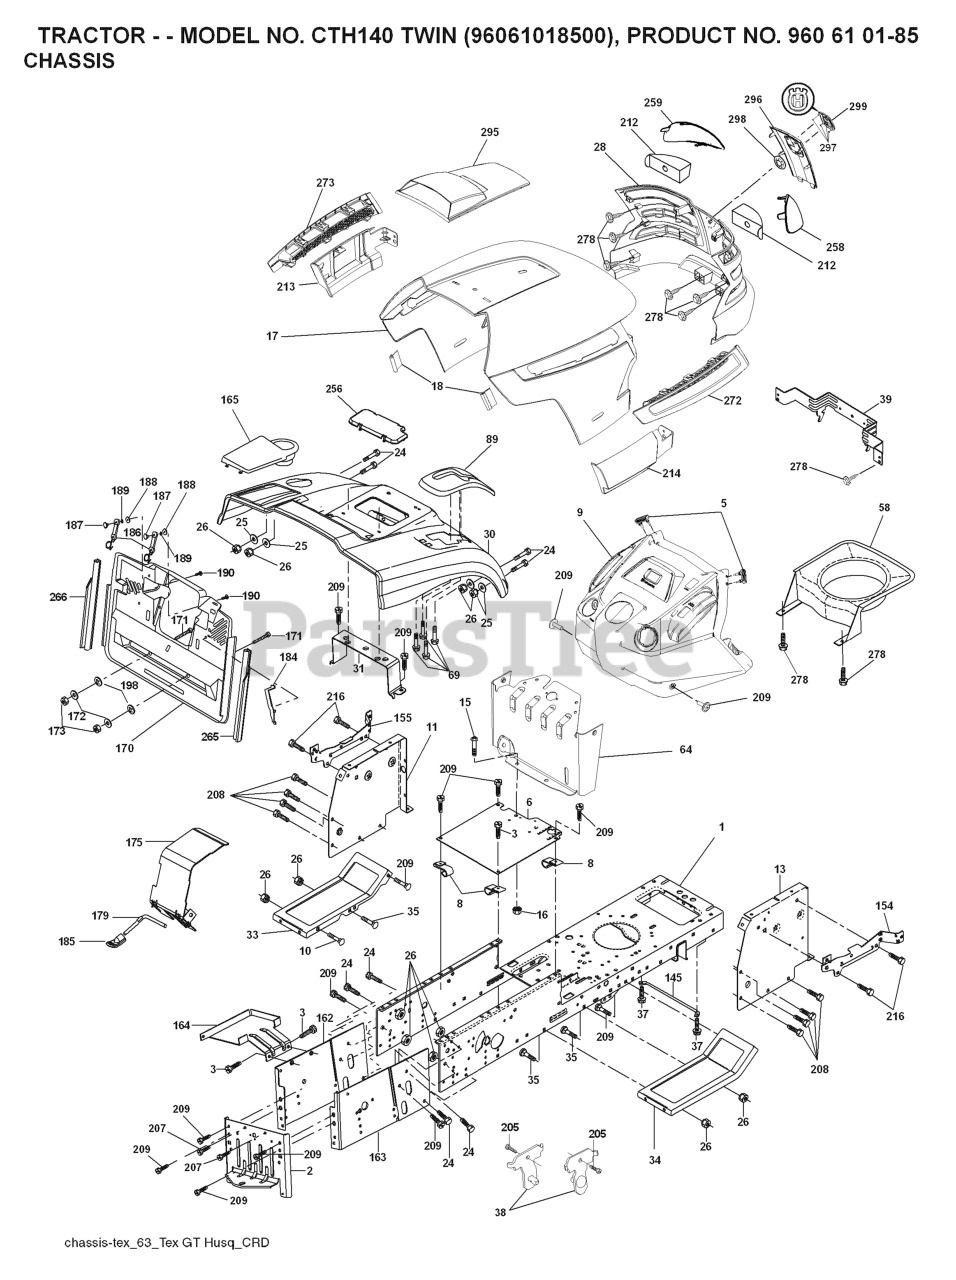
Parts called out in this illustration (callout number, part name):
2	DRAWBAR
3	SCREW 3/8-16X3/4
5	BUMPER DASH
6	PLATE
8	CLIP,INSULATOR
10	BOLT D
11	PANEL.DASH.LH.LTX
13	PANEL ASM, DASH RH
15	Screw, Machine, Truss Head 5/16-18 UNC x 3/4
16	NUT
17	HOOD
18	BUMPER.HOOD.TEX.HUSQVARNA
25	WASHER
26	NUT
28	RP GRILLE/LENS ASM.
30	CONSOLE.CRD.AUTO.GRY
31	BRACKET SUPPORT FENDER
33	FOOTREST PNT LH
34	FOOTREST PNT RH
37	Screw 5/16-18 x 1/2 Hex, Self Tapping 5/16-18 x 1/2
38	BRACKET ASM PIVOT MOWER REAR
39	BRACKET PIVOT
69	SCREW.HI-LO.CONSOLE
89	CONSOLE.CRD.AUTO.GREY.2005
145	ROD PIVOT CHASSIS/HOOD
162	BRACKET
163	BRACKET EXTEN CHASSIS RH CRD
165	RP.COVER.BATTERY.CRD.GREY
172	WASHER
175	DOOR TRAP
179	ROD PIVOT FBI
184	BRACKET.ACTUATOR.BAGGER.SRD
186	LATCH ASSY
187	WELDNUT
189	LOCKWASHER #10
190	SCREW
207	SCREW, 5/16-18 X 1/2
208	SCREW 3/8-16X1/2
209	SCREW, 3/8-16X3/4
212	INSERT REFLECTIVE
213	SKIRT SIDE LH
214	SKIRT SIDE RH
216	SCREW HEXWSHR 1/4-20X3/4
256	COVER FENDER CRD
258	LENS.HUSQVARNA LT.RH
259	LENS.HUSQVARNA LT.LH
265	SEALING
266	SEALING
272	VENT SIDE HOOD RH
273	VENT SIDE HOOD LH
278	SCREW
295	VENT TOP HOOD
296	TRIM
297	CLIP.RETAINER.TINNER.
298	NUT PUSH M
299	RP LOGO
